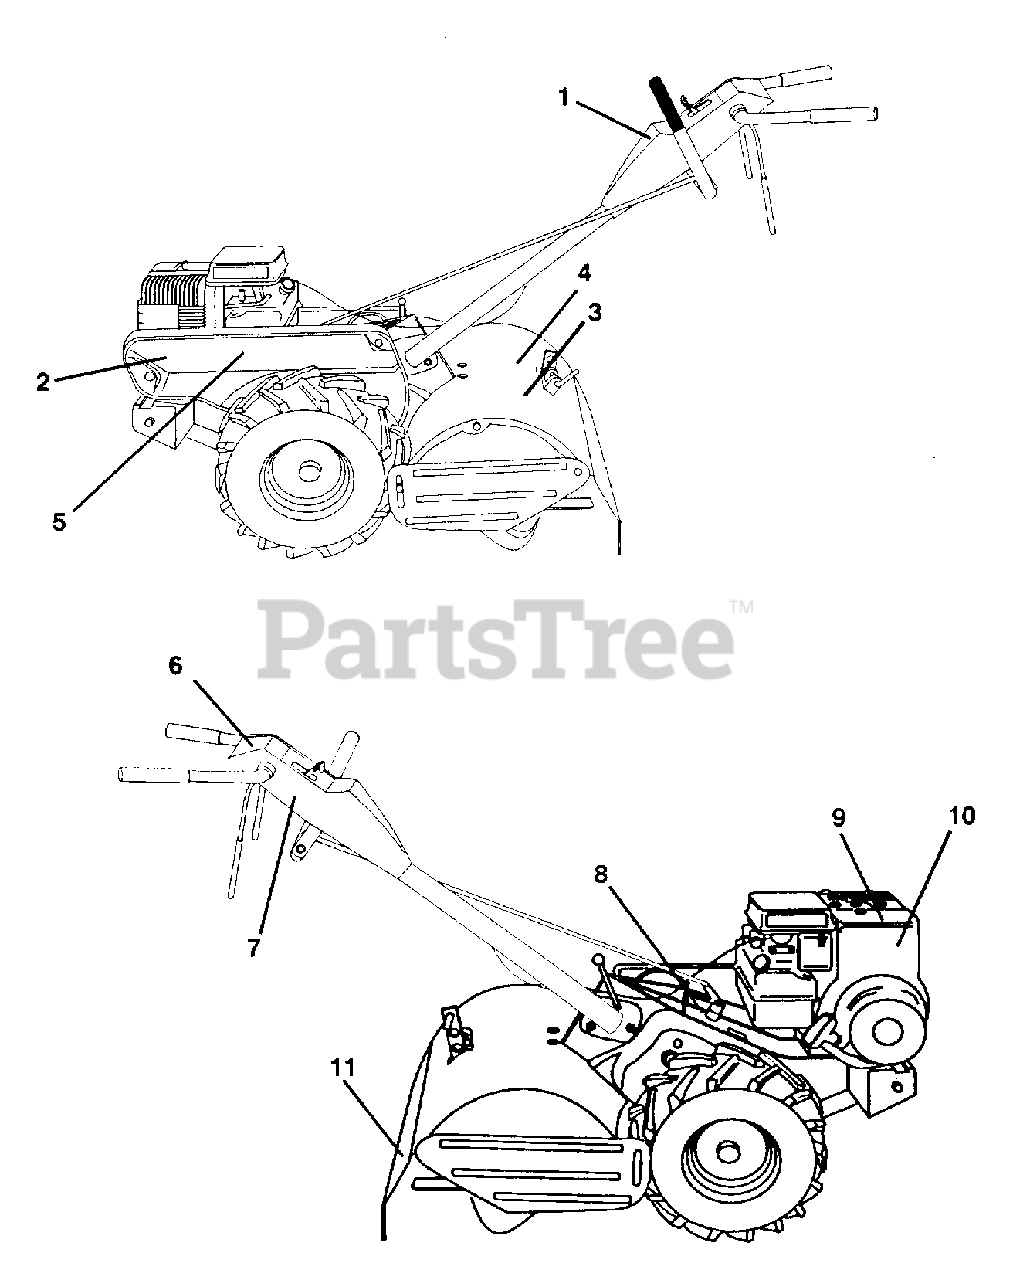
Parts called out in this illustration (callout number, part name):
1	DECAL.CNTRL.PANEL
2	DECAL, LOGO (BELT GUARD)
3	DECAL, TINE SHIELD
4	DECAL, LOGO (TINE SHIELD)
5	NAMEPLATE LOGO
6	DECAL.INSTRUCTION
7	DECAL TI
8	DECAL CRT
11	DECAL TI
